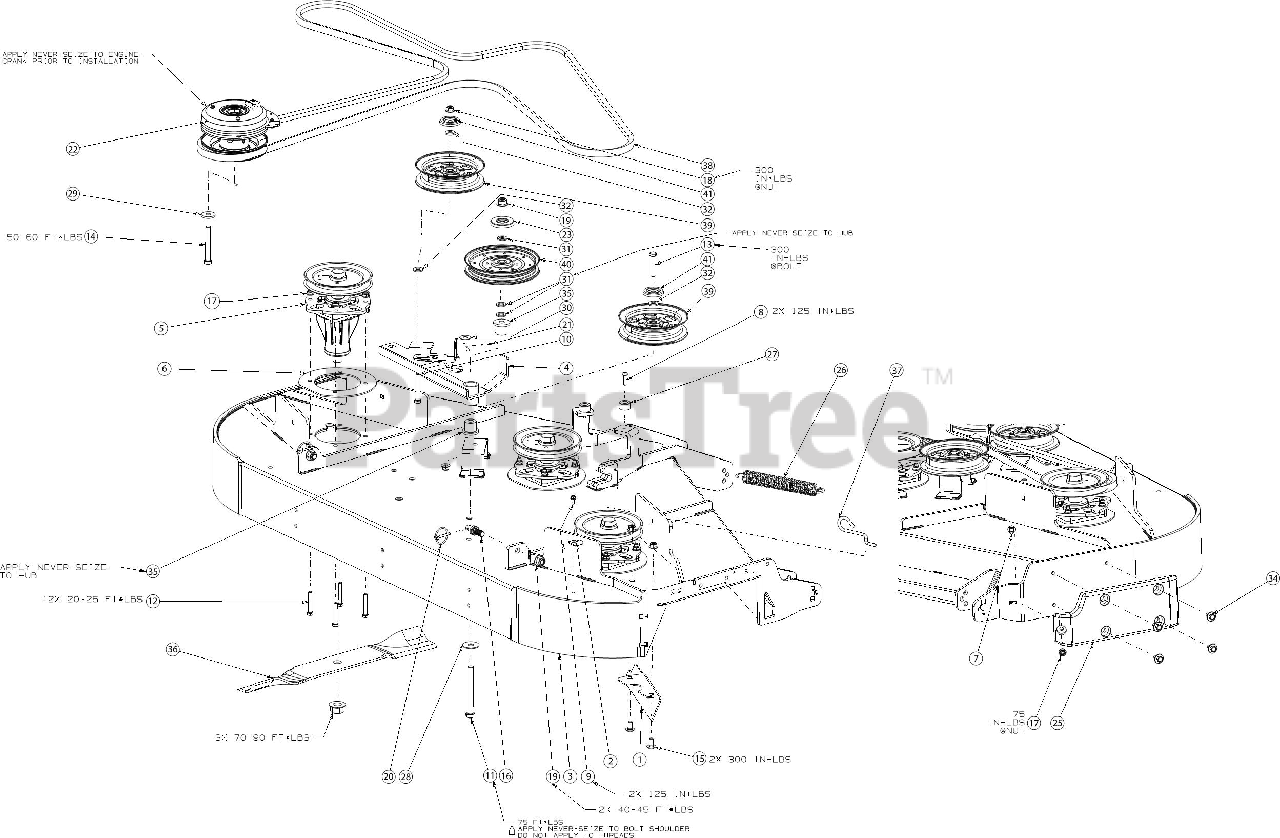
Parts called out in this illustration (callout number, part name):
2	HOOK RETAINER BRACKET
4	IDLER ARM ASSEMBLY
5	SPINDLE ASSEMBLY
6	SPINDLE REINFORCEMENT PLATE
7	CARRIAGE BOLT 5/16-18 x 1.00
8	SCREW 1/4-20 x 1.0
9	SCREW 1/4-20 X.500
10	HEX SCREW-3/8-16X2.5 GR5
11	SCREW 1/2-13 x 4.5 GR 5
12	SCREW 5/16-18 x 2.0 GR5
13	SCREW 3/8-16 x 2.0 GR5
14	SCREW 7/16-20 x 3.25 GR5
15	CARRIAGE BOLT 3/8-16 x .75
17	FLANGE LOCK NUT 5/16-18
21	COTTER PIN 3/32
22	ELECTRIC PTO CLUTCH
23	PULLEY CAP 1/2"
24	CABLE TIE 18"
25	DECK SKID PLATE (LH)
26	EXTENSION SPRING
28	WASHER .51 x 1.5 x .07
29	FLAT WASHER .445 x 1.248 x .170
30	FLAT WASHER
31	FLAT WASHER
32	FLAT WASHER
34	SHOULDER SCREW .43X.29X5/16-18 TT
35	SHOULDER SPACER
36	21" BLADE (HI LIFT)
37	DECK SPRING HOOK
38	DECK BELT B x 161.75
39	IDLER PULLEY 5.0
40	IDLER PULLEY 6.0" DIA
41	IDLER PULLEY CAP
